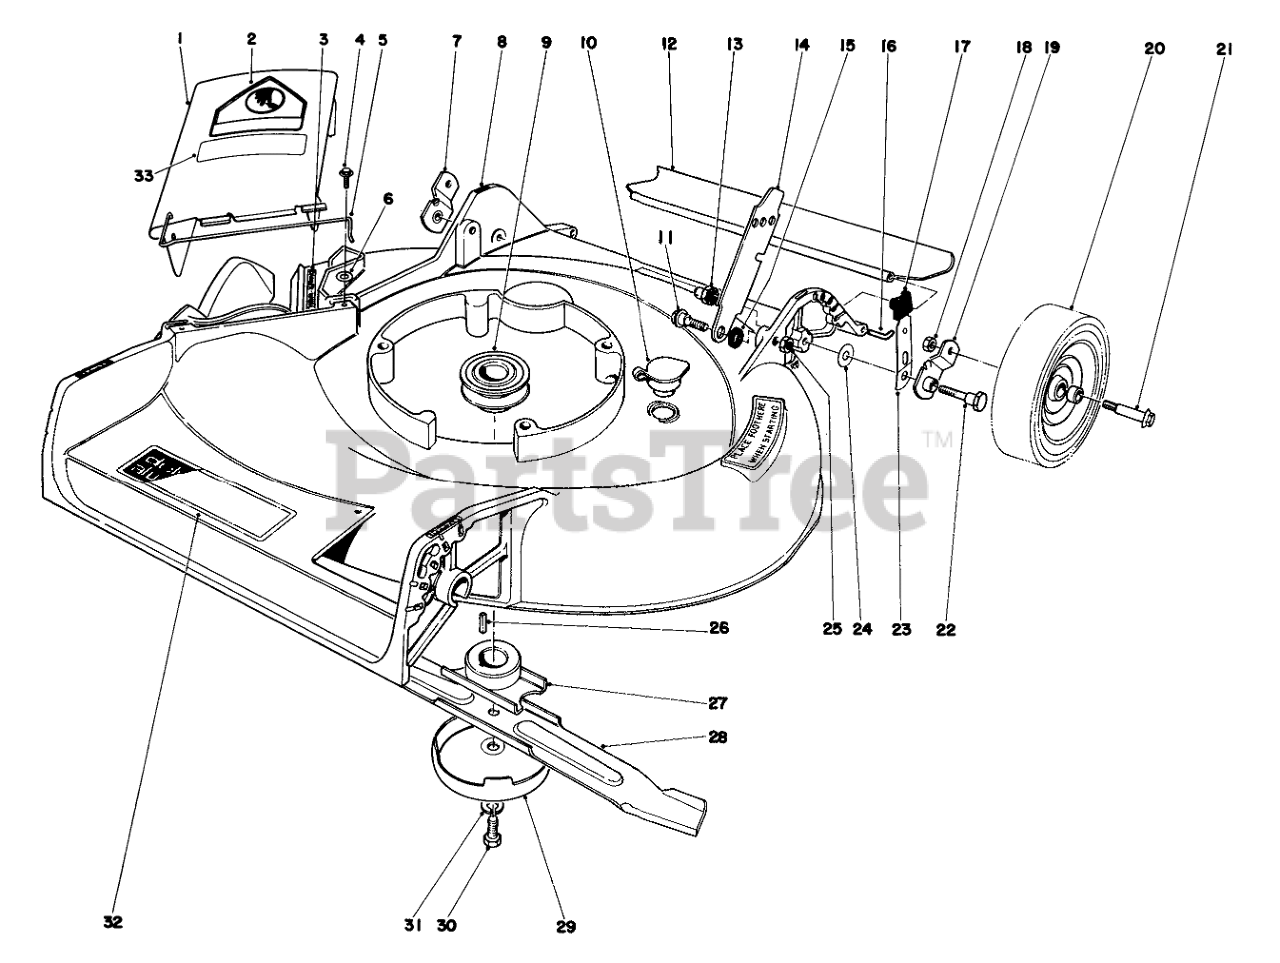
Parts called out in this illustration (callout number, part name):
1	Deflector Cover Assembly (Incl. Ref. #2 & 5)
2	DECAL-DANGER
3	Decal
4	SCREW
5	SPRING HINGE
6	WASHER-FLAT
7	Pivot Arm
8	Housing
9	DRIVER PULLEY
10	Plug Washout
11	SCREW-SHOULDER
12	Rear Shield
13	HANDLE PIVOT NUT
14	Latch
15	HANDLE LATCH SPACER
16	SHIELD ROD
17	KNOB-ARM
18	Nut
19	Pivot Arm
20	Wheel & Tire Assembly
22	5/16-18 PIVOT SCREW
23	SPRING ARM ASM
24	Washer
25	Nut
26	KEY-SQUARE
27	Blade Retailer
28	Blade
29	Anti Scalp Cup
30	SPECIAL SCREW
31	22 Lockwasher
32	Decal-Deck
33	Decal Caution
